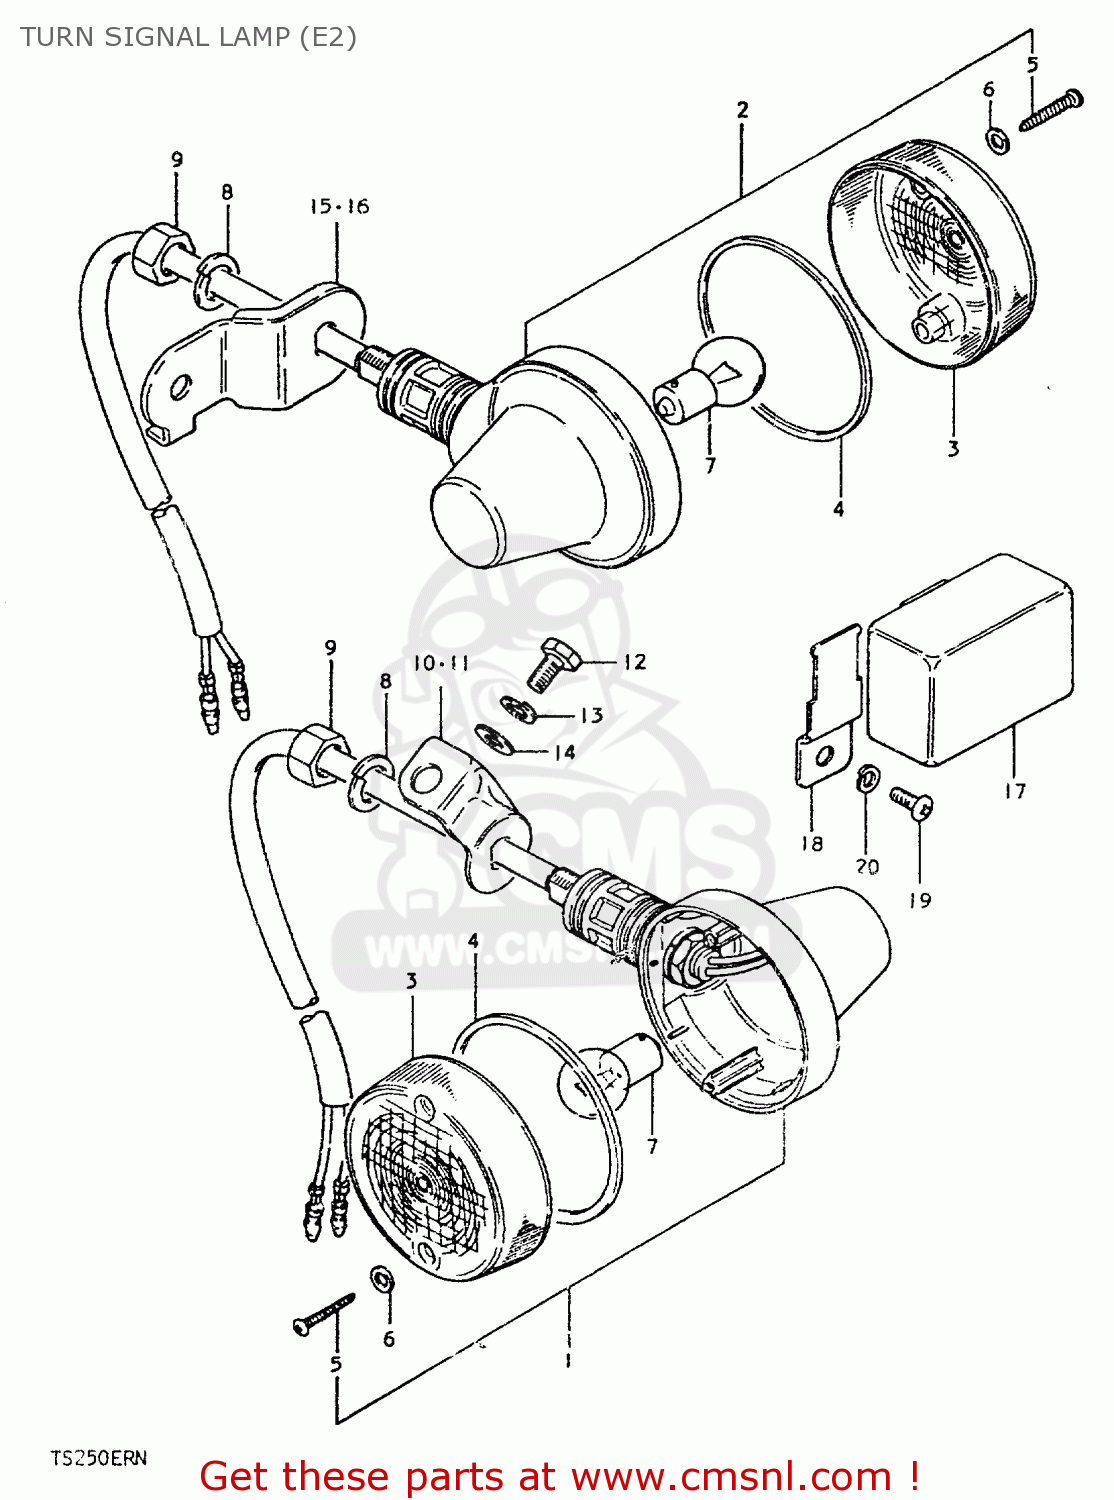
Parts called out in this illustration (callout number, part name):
1	LAMP ASSY,RR TURNSIGNAL
2	LAMP ASSY,RR TURNSIGNAL
3	LENS
4	GASKET (NAS)
5	SCREW TAPP.
6	GASKET (NAS)
7	BULB (6V,18W)
8	WASHER,LOCK 12
9	NUT
10	BRACKET,TURN SIGNAL LAMP
11	BRACKET,TURN SIGNAL LAMP
12	BOLT
13	LOCK WASHER
14	WASHER
15	BRACKET,REAR TURN SIGNAL
16	BRACKET,REAR TURN SIGNAL
17	RELAY,TURN SIGNAL
18	BRACKET,TURN SIGNAL RELAY
19	SCREW 6X12
20	LOCK WASHER
